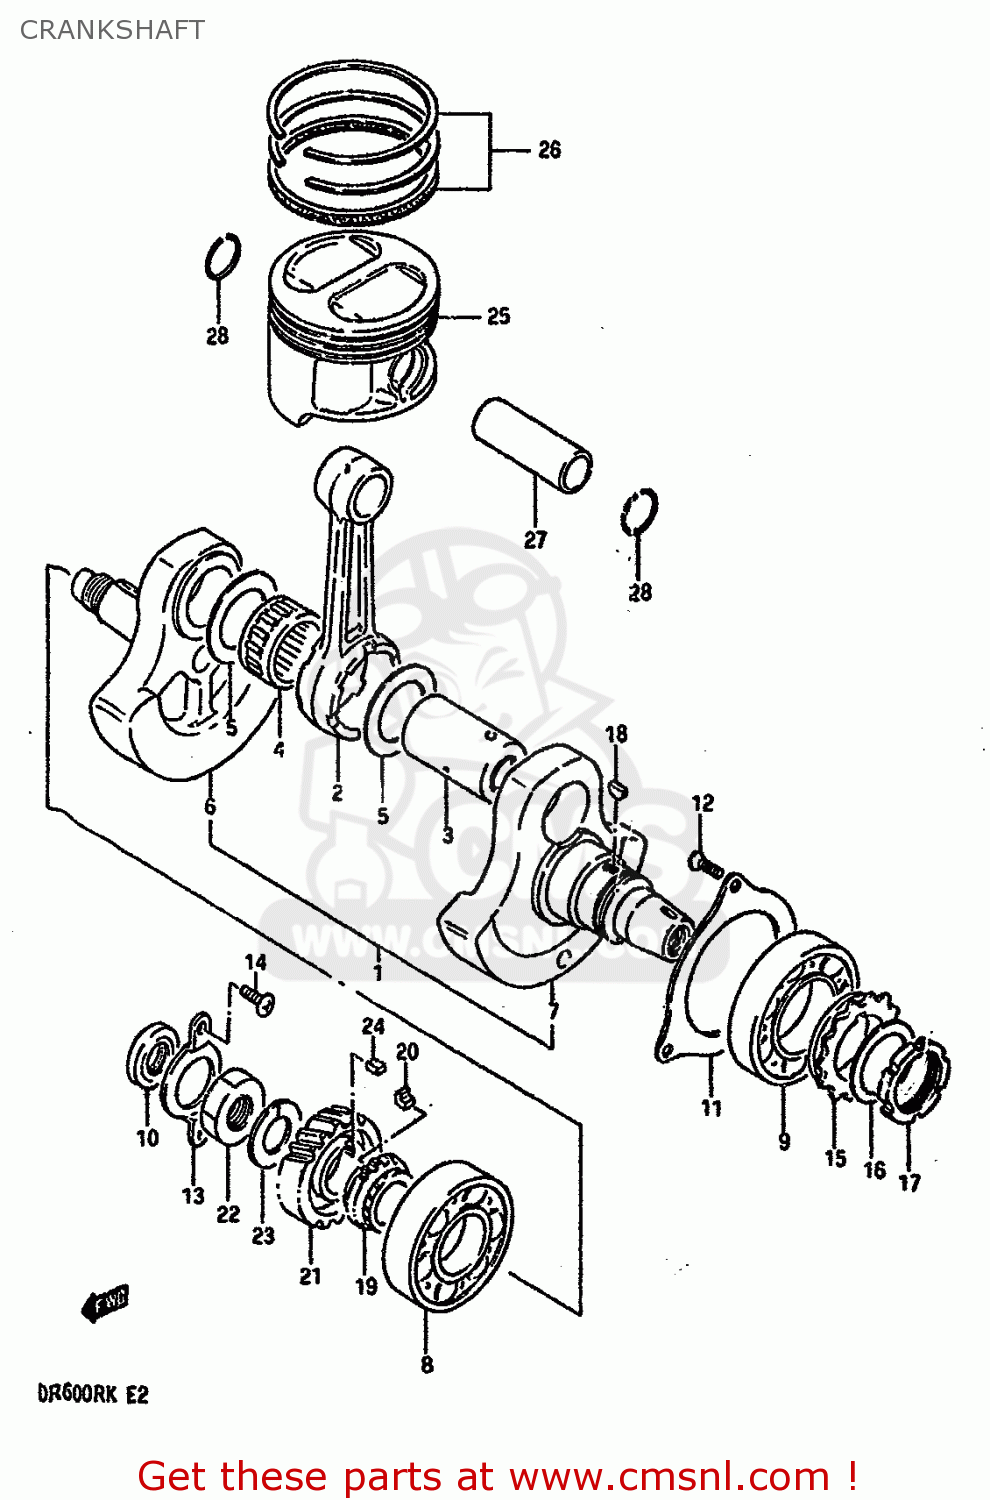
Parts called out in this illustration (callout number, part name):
1	CRANKSHAFT ASSEMBLY
2	CONNECTING ROD
3	PIN,CRANK
4	BEARING
5	WASHER(37X55X1)
6	CRANKSHAFT,RIGHT
7	CRANKSHAFT,LEFT
8	BEARING(35X80X21)
9	BEARING
10	SEAL,OIL(16X30X6)
11	RETAINER,CRANKSHAFT BEARING,L
12	SCREW
13	RETAINER,CRANKSHAFT BEARING,R
14	SCREW
15	SPROCKET,BALANCER DRIVE
16	WASHER
17	NUT,FLYWHEEL
18	KEY
19	SPROCKET,CAM CHAIN DRIVE
20	KEY,SPROCKET
21	GEAR,PRIMARY DRIVE
22	NUT (20MM)
23	WASHER
24	KEY
25	PISTON (OS:0.5)
26	RING SET,PISTON
27	PIN,PISTON
28	CIRCLIP
